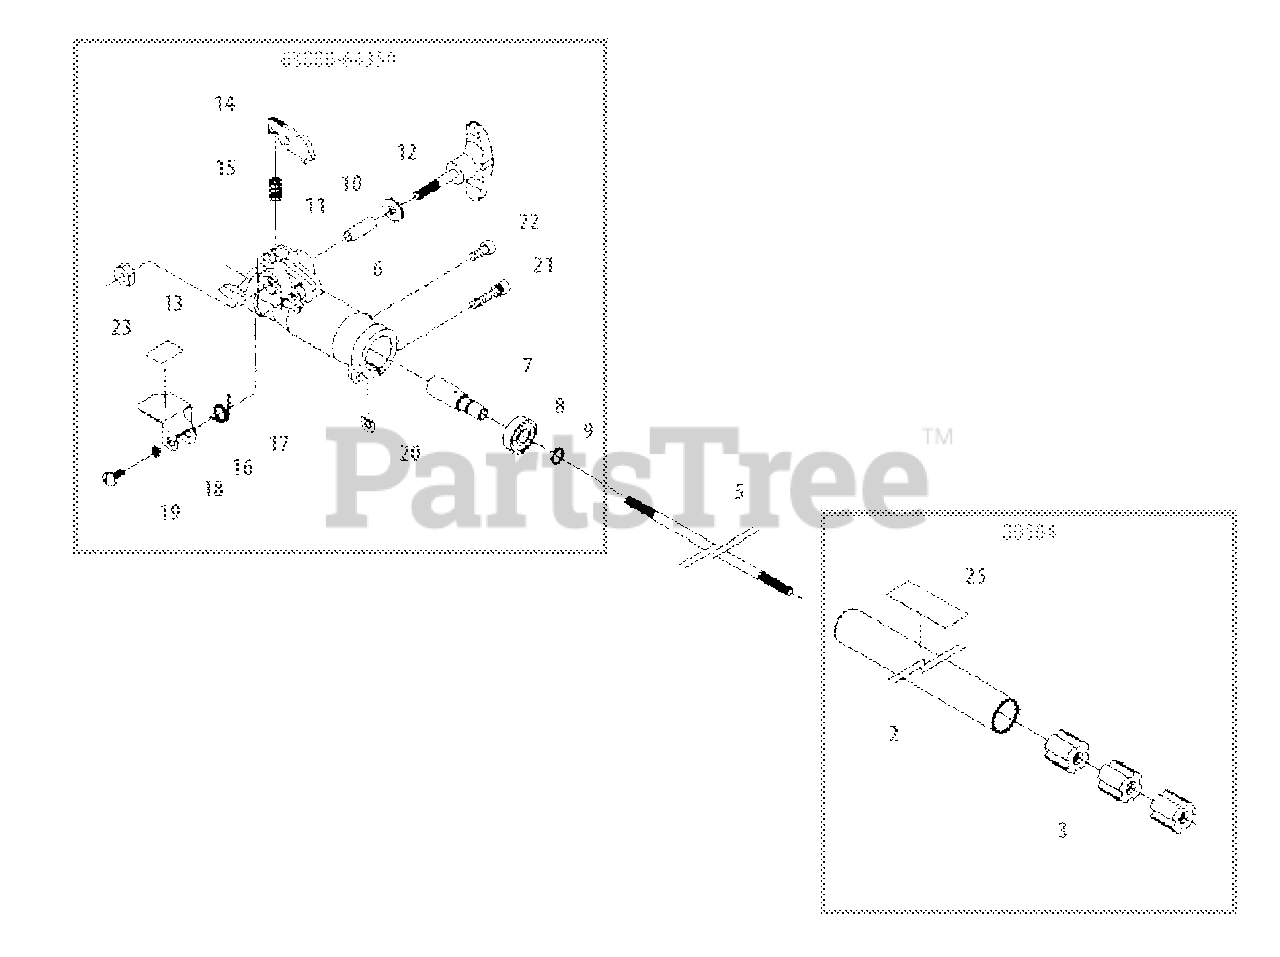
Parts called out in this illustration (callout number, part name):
2	PIPE, MAIN
3	BUSHING
5	MAINSHAFT
6	HOUSING, COUPLER
7	SHAFT, COUPLER
8	BEARING, BALL 609ZZ
9	RING, SNAP
10	WASHER 6
11	COLLAR
12	KNOB, COUPLER SCREW
13	NUT 6
14	LATCH
15	SPRING
16	PROTECTOR, LATCH
17	SPRING, TORSION
18	WASHER 5
19	SCREW M5×12
20	D-WASHER
21	SCREW
22	BOLT 5×12
23	LABEL, LATCH INSTRUCTION
25	LABEL - CAUTION
63880-64350	COUPLER ASSY
80504	MAIN PIPE ASSY
